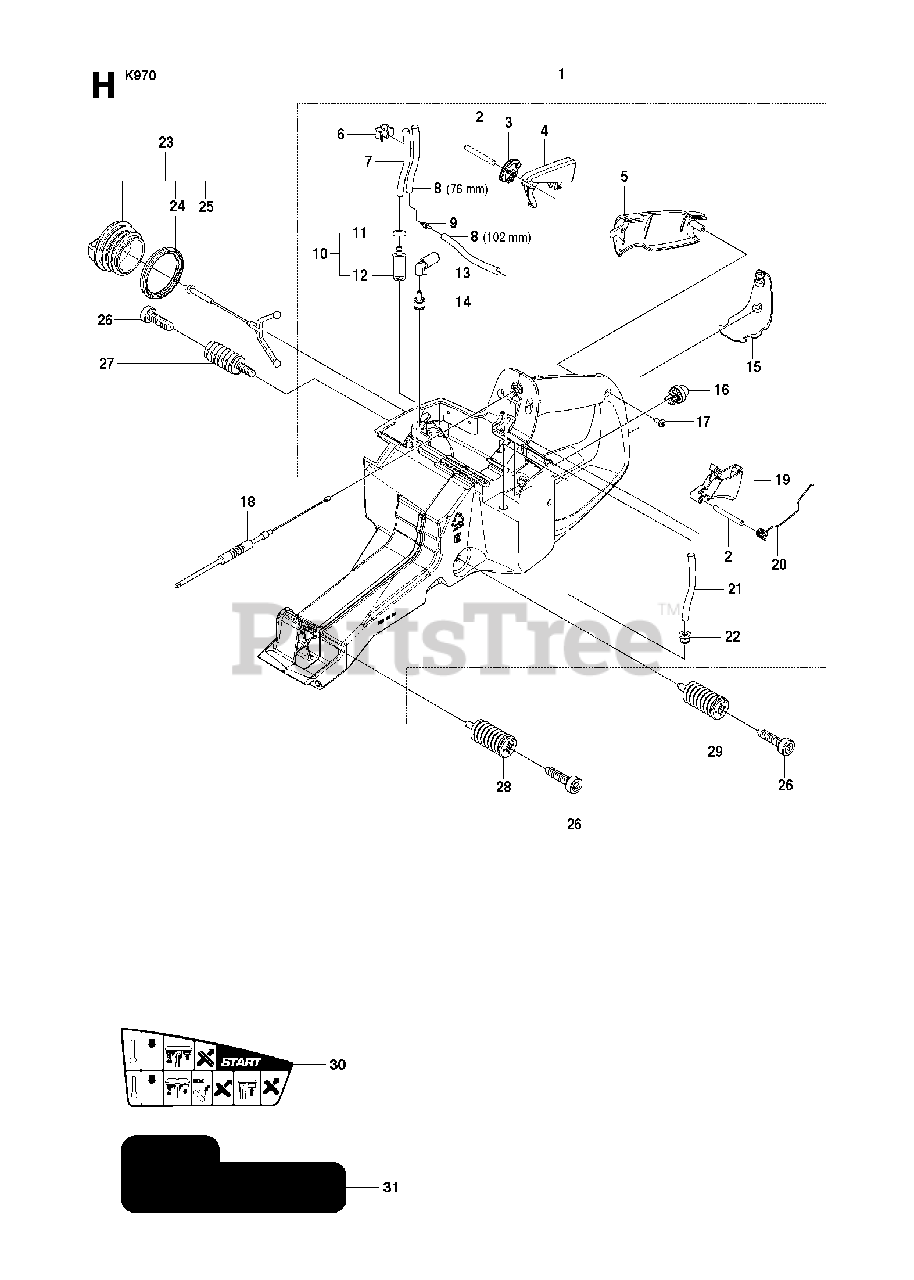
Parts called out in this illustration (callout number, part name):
1	FUEL TANK ASSY
2	PARALLEL PIN
4	THROTTLE LOCKOUT
7	FUEL HOSE
8	FUEL HOSE
13	HOLDER ASSY
14	TANK VENT ASSY
15	GROUND SUPPORT
17	SCREW CCRPANT
18	THROTTLE CABLE ASSY
19	THROTTLE CONTROL
21	FUEL HOSE
22	BUSHING
23	TANK CAP ASSY
26	SCREW ITXSCM
27	ANTIVIBRATION ELEMENT
28	ANTIVIBRATION ELEMENT
29	ANTIVIBRATION ELEMENT
